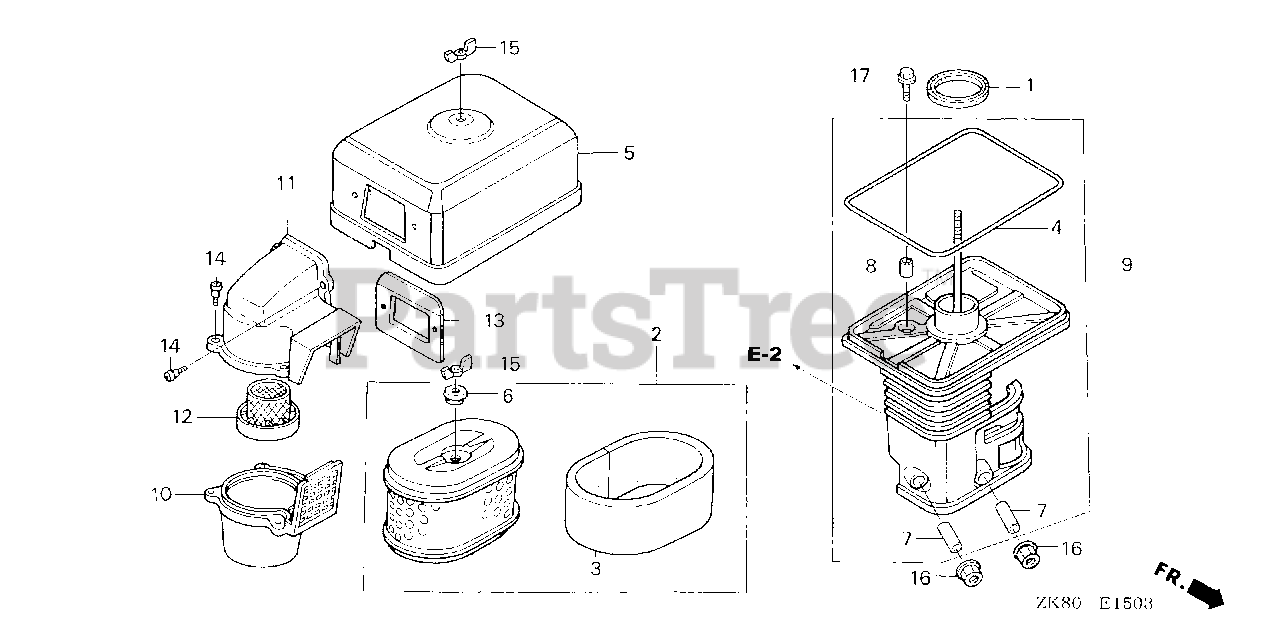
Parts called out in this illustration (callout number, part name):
1	GASKET, ELBOW
2	ELEMENT, AIR CLEANER (DUAL)
3	FILTER (OUTER)
4	GASKET, AIR CLEANER COVER
5	COVER, AIR CLEANER (DUAL)
6	GROMMET, AIR CLEANER
7	COLLAR, AIR CLEANER
8	COLLAR B, AIR CLEANER
9	ELBOW, AIR CLEANER
10	CASE, PRE AIR CLEANER
11	CAP, PRE AIR CLEANER
12	GUIDE, PRE AIR CLEANER
13	PLATE, PRE AIR CLEANER
14	BOLT, SPLASH GUARD
15	NUT, TOOL BOX SETTING
16	NUT, FLANGE (6MM)
17	BOLT, FLANGE (6X20)
